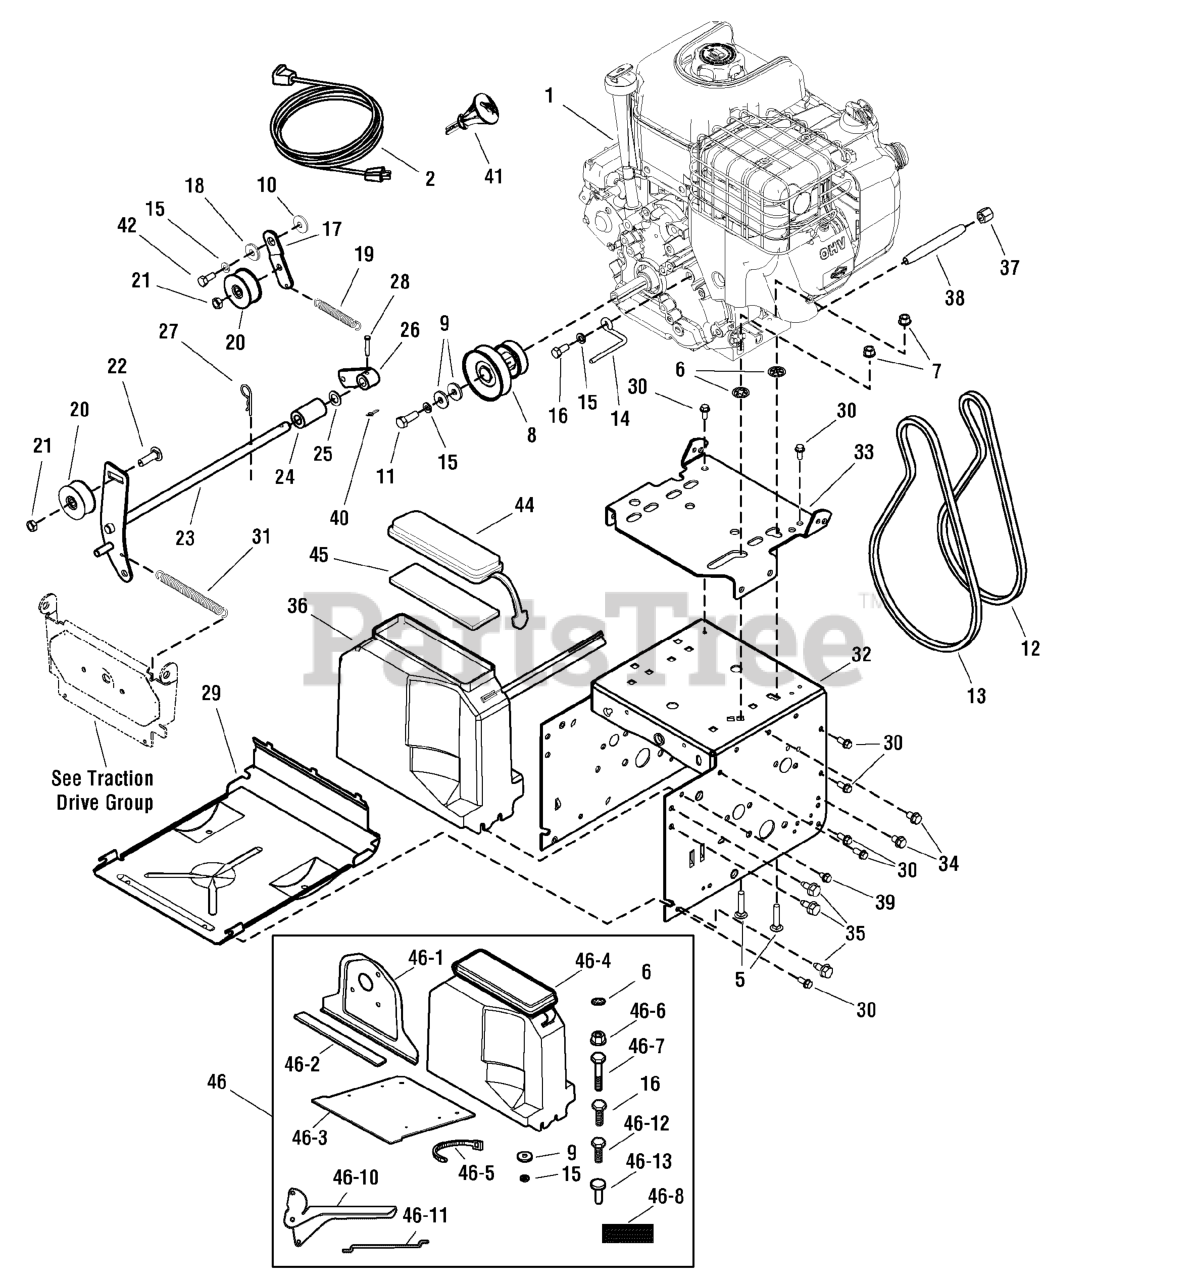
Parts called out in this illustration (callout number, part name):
2	CORD, Electric, 10FT. 110V
5	BOLT, Carriage, 5/16-18 x 1-1/2
6	NUT, Speed, 1/4
7	NUT, Hex Flange, 5/16-18 Whiz Lock Small
8	PULLEY, Engine
9	WASHER, Flat, 3/8
10	WASHER, Locking, 3/8
11	CAPSCREW, Hex-Head, 3/8-24 x 1-1/4
12	V-BELT, Drive, 3L
13	V-Belt, Auger, 4L
14	GUIDE, Belt
15	WASHER, Locking, 5/16
16	BOLT, Hex-Head, 5/16-24 x 3/4
17	ASSEMBLY, Idler Bracket
18	BUSHING, Idler Bracket
19	SPRING, Extension
20	IDLER, Plastic, Ball Bearing
21	NUT, Hex-Jam, 3/8-16
22	BOLT, Carriage, 3/8-16 x 1-1/4
23	IDLER ASSEMBLY, AUGER
24	SPACER, Auger Idler
25	WASHER, Flat, 1/2
26	ASSEMBLY, Spring Attachment
27	PIN, Hair
28	PIN, Clevis
29	PANEL, Bottom
30	SCREW, 1/4-20 x 5/8
31	SPRING, Extension
32	FRAME, Steerable
33	ENGINE MOUNT
34	SCREW, 3/8-18 x 1/2
35	SCREW, 3/8-18 x 3/4
36	COVER, Belt
37	CAP, Pipe
38	PIPE, Oil Drain
39	SCREW, Hex-Washer, 1/4 x 3/4, Self-Tapping
40	PIN, Cotter, 1/4, Self-Locking
41	KEY, Ignition
42	SCREW, 5/16-24 x 1.00
44	LID, Toolbox
45	PAD, Foam
46	KIT, Drive Seal
46-1	SEAL PLATE
46-2	SEAL STRIP
46-3	SEAL, Engine Plate
46-4	BELT COVER
46-5	TIE, Self Locking
46-6	NUT, Hex Flange Two-Way Lock, 5/16-18
46-7	SCREW, 5/16-24 x 1.00
46-8	DECAL, Hinge
46-10	CLUTCH LEVER
46-11	ROD, Hold down
46-12	CAPSCREW, Hex Head 1/4-20 x 1-3/4 G5
46-13	SPACER, 1/4 ID x 3/8 OD 1" Long
